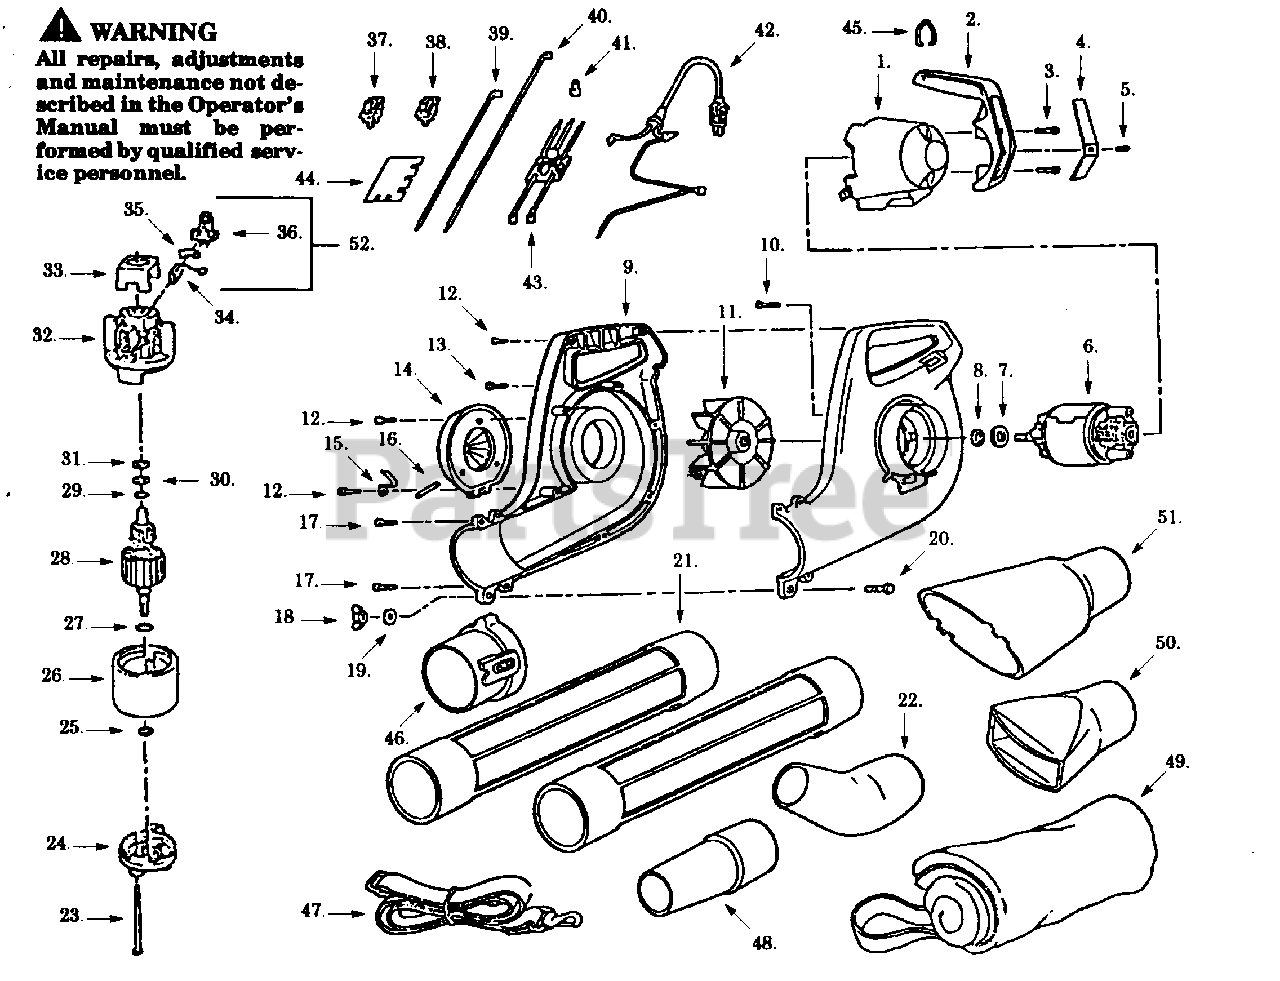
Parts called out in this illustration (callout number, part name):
1	Motor Cover
8	Retaining Ring
9	R.H./L.H. Housing
11	Impeller Ass'y.
14	Inlet Cover
16	Hinge Pin
18	Wing Nut
21	Outlet Tube
22	Curved Nozzle
24	Endbell Ass'y. (Drive)
26	Field Ass'y.
27	Retaining Ring
28	Armature Ass'y.
29	Retaining Ring
32	Endbell Ass'y. (Brush)
33	Insulator
35	Brush Spring
36	Brush Holder
37	On-Off Switch
38	Speed Switch
39	Leadwire Ass'y.
40	Leadwire Ass'y.
41	Connector
42	Power Cord Ass'y.
43	P.C. Board Ass'y.
44	Mounting Board
46	Adapter Tube Ass'y.
47	Shoulder Strap
49	Vacuum Bag
50	Diffuser Nozzle
51	Vacuum Nozzle Ass'y.
52	Brush Kit (Incl. 34,35,36)
